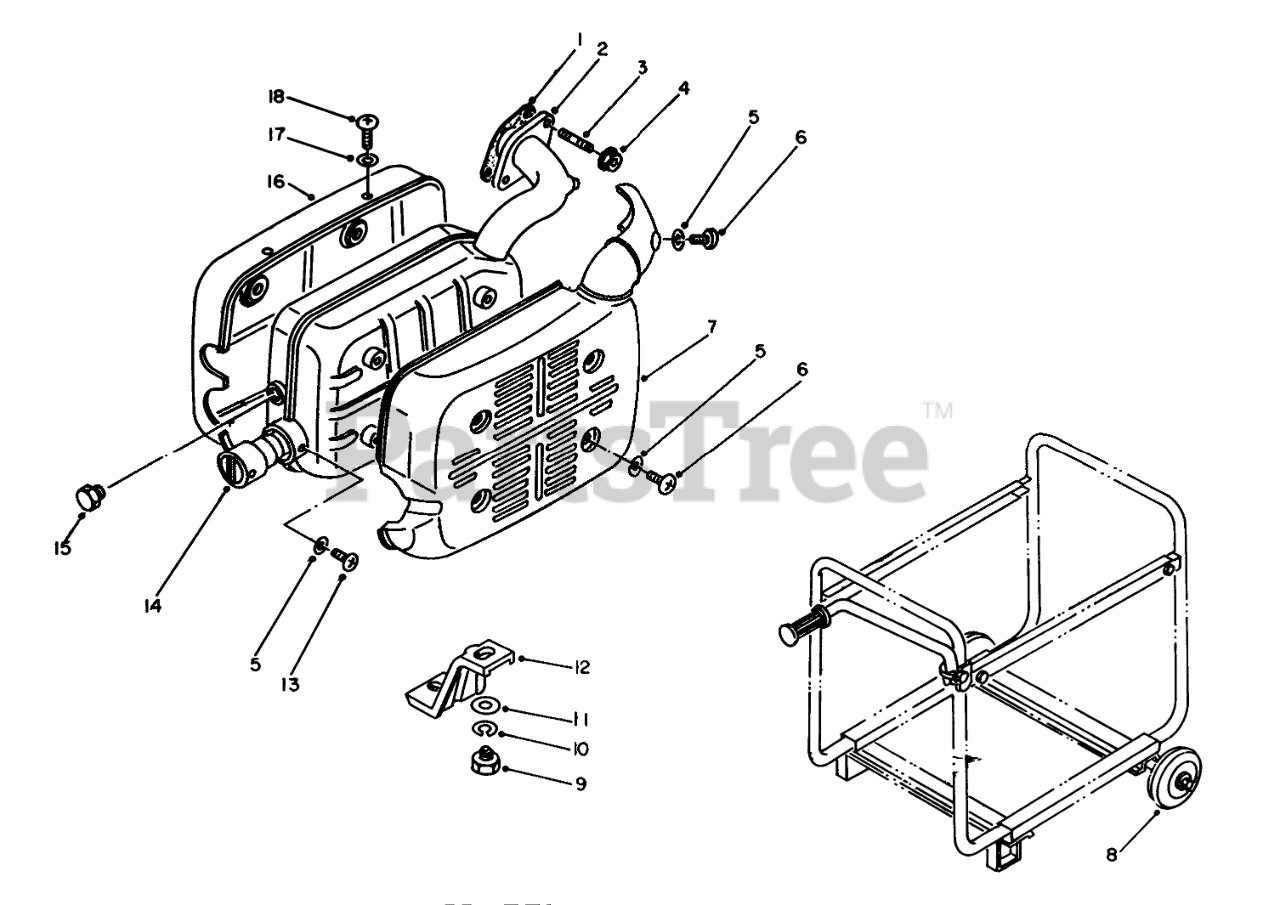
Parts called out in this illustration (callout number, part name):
1	EX GASKET
2	MUFFLER ASM
3	Stud Bolt
4	M6 X 1 LOCKNUT
5	Lockwasher
6	SCREW
7	Cover-Front
8	Wheel Assembly (Optional)
10	WASHER-LOCK
11	Washer
12	Bracket
13	Screw
14	Cleanout Tube
15	Drain Plug
16	Cover-Rear
17	Lockwasher
18	Screw
